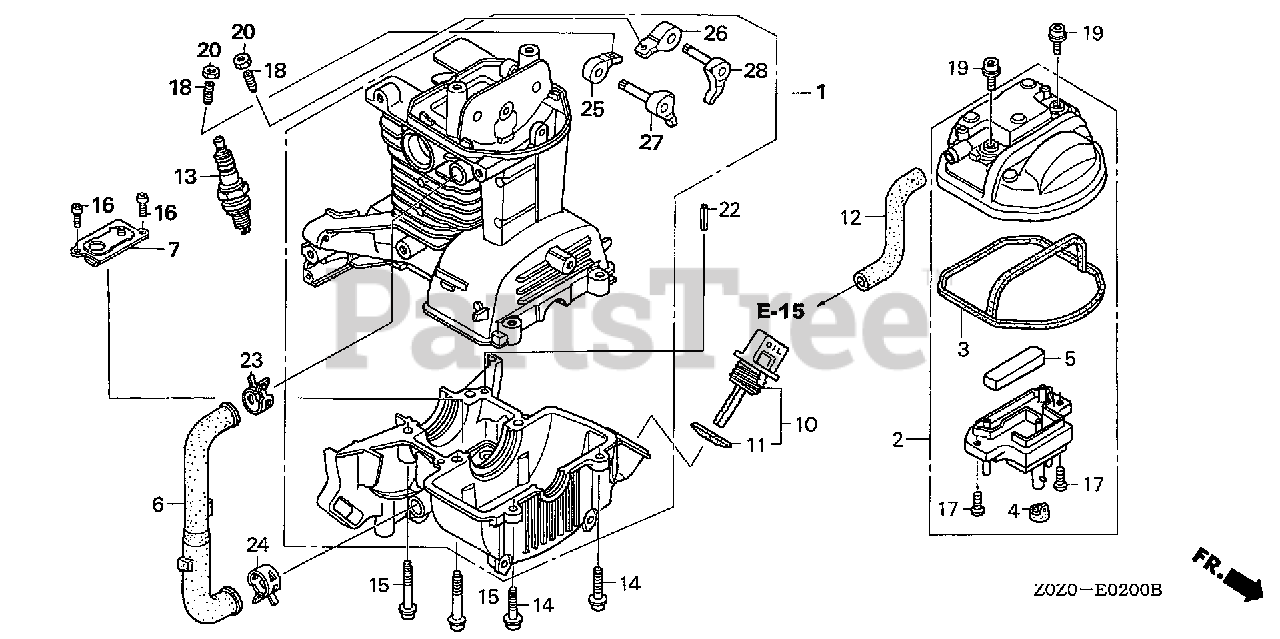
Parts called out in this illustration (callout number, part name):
1	CRANKCASE SET
2	COVER, CYLINDER HEAD
3	SEAL, HEAD COVER
4	GROMMET, HEAD COVER
5	FILTER, BREATHER
7	PLATE ASSY., OIL OUTLET VALVE
10	CAP ASSY., OIL FILLER
11	GASKET, OIL FILLER CAP
12	TUBE, BREATHER
13	SPARK PLUG (CMR4H) (NGK)
13	SPARK PLUG (CMR5H) (NGK)
13	SPARK PLUG (CMR6H) (NGK)
14	BOLT, SOCKET (5X20)
15	BOLT, SOCKET (5X32)
16	SCREW, PAN (4X8)
17	SCREW, PAN (4X8)
18	SCREW, TAPPET ADJUSTING
19	BOLT, SOCKET (5X12)
20	NUT, TAPPET ADJUSTING
22	PIN, SPRING (4X10)
23	CLAMP, TUBE (D12)
24	CLAMP, TUBE (D13)
25	ARM, IN. VALVE ROCKER
26	ARM, EX. VALVE ROCKER
27	LIFTER, IN. VALVE
28	LIFTER, EX. VALVE
